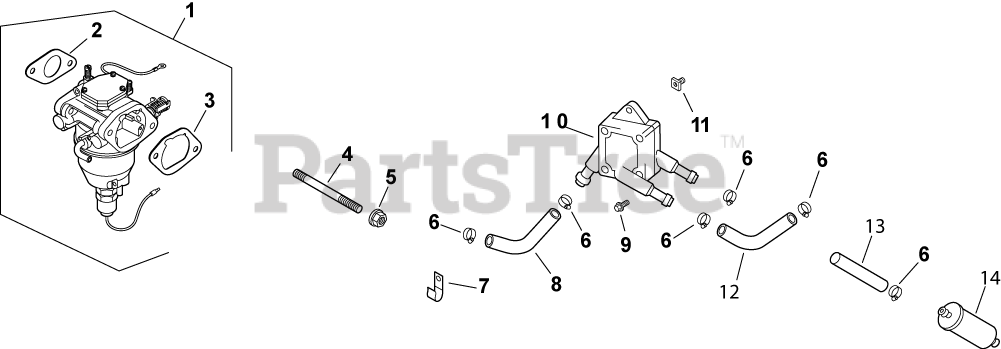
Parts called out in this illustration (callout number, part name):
1	KIT, CARBURETOR W/GASKET
2	GASKET, CARBURETOR
3	GASKET, AIR CLEANER BASE
4	STUD,M6X1.0X128
5	NUT, FLG M6X1.0
6	CLAMP, HOSE (KM)-USE 25 237 31-S
7	CLIP, CABLE
8	HOSE,LW PERM.FUEL 24.00"-USE 25 111 81-S
9	SCREW, TAP M6X1.7X18
10	PUMP, FUEL
11	NUT, PLASTIC (KM)-USE 25 100 37-S
12	LINE, FLEXIBLE FUEL
13	LINE, FUEL 11"
14	FILTER,FUEL 51 MICRON (FUEL PUMP)
